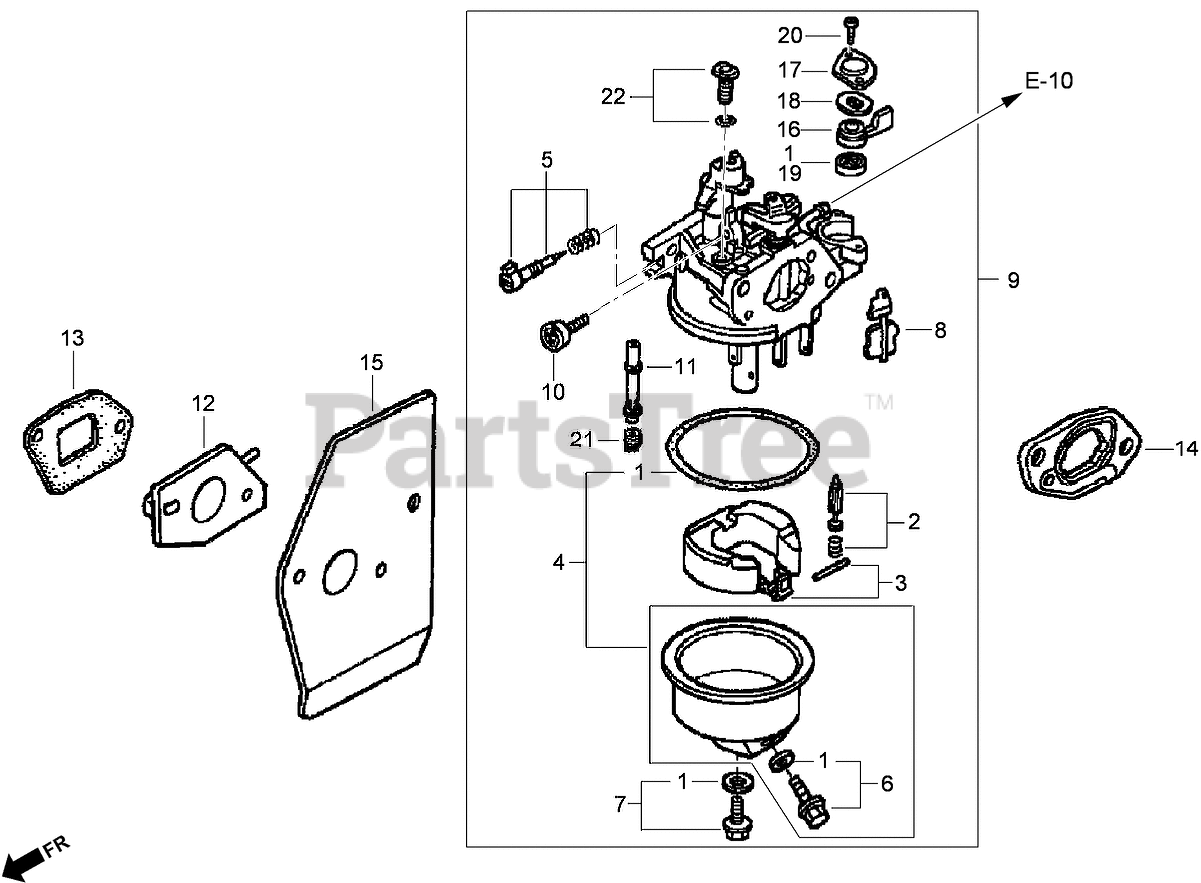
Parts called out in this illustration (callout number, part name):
1	GASKET SET
2	FLOAT VALVE SET
3	FLOAT SET (CARBURETOR NO. BE66J A)
3	FLOAT SET (CARBURETOR NO. BE66N A)
4	FLOAT CHAMBER SET
5	PILOT SCREW SET
6	DRAIN SCREW SET
7	SCREW SET
8	CHOKE SET (CARBURETOR NO. BE66J A)
8	CHOKE SET (CARBURETOR NO. BE66N A)
9	CARBURETOR ASM (BE66J A) (Engine Serial No. Up To 1001679)
9	CARBURETOR ASM (BE66N A) (Engine Serial No. From 1001680)
10	SCREW- STOP, THROTTLE
11	NOZZLE-MAIN (CARBURETOR NO. BE66J A)
11	NOZZLE-MAIN (CARBURETOR NO. BE66N A)
12	Insulator-Carburetor
13	Gasket-Insulator
14	Spacer-Carburetor
15	Gasket-Carburetor
16	LEVER-PETCOCK
17	PLATE-SETTING, LEVER
18	SPRING-LEVER, PETCOCK
19	GASKET-PETCOCK
20	SCREW-PAN (3X6)
21	JET-MAIN (No. 60) (CARBURETOR NO. BE66J A)
21	JET-MAIN (No. 62)
21	JET-MAIN (No. 65) (CARBURETOR NO. BE66J A)
21	JET-MAIN (No. 65) (CARBURETOR NO. BE66N A)
21	JET-MAIN (No. 68) (CARBURETOR NO. BE66N A)
22	PILOT JET SET (No. 35)
